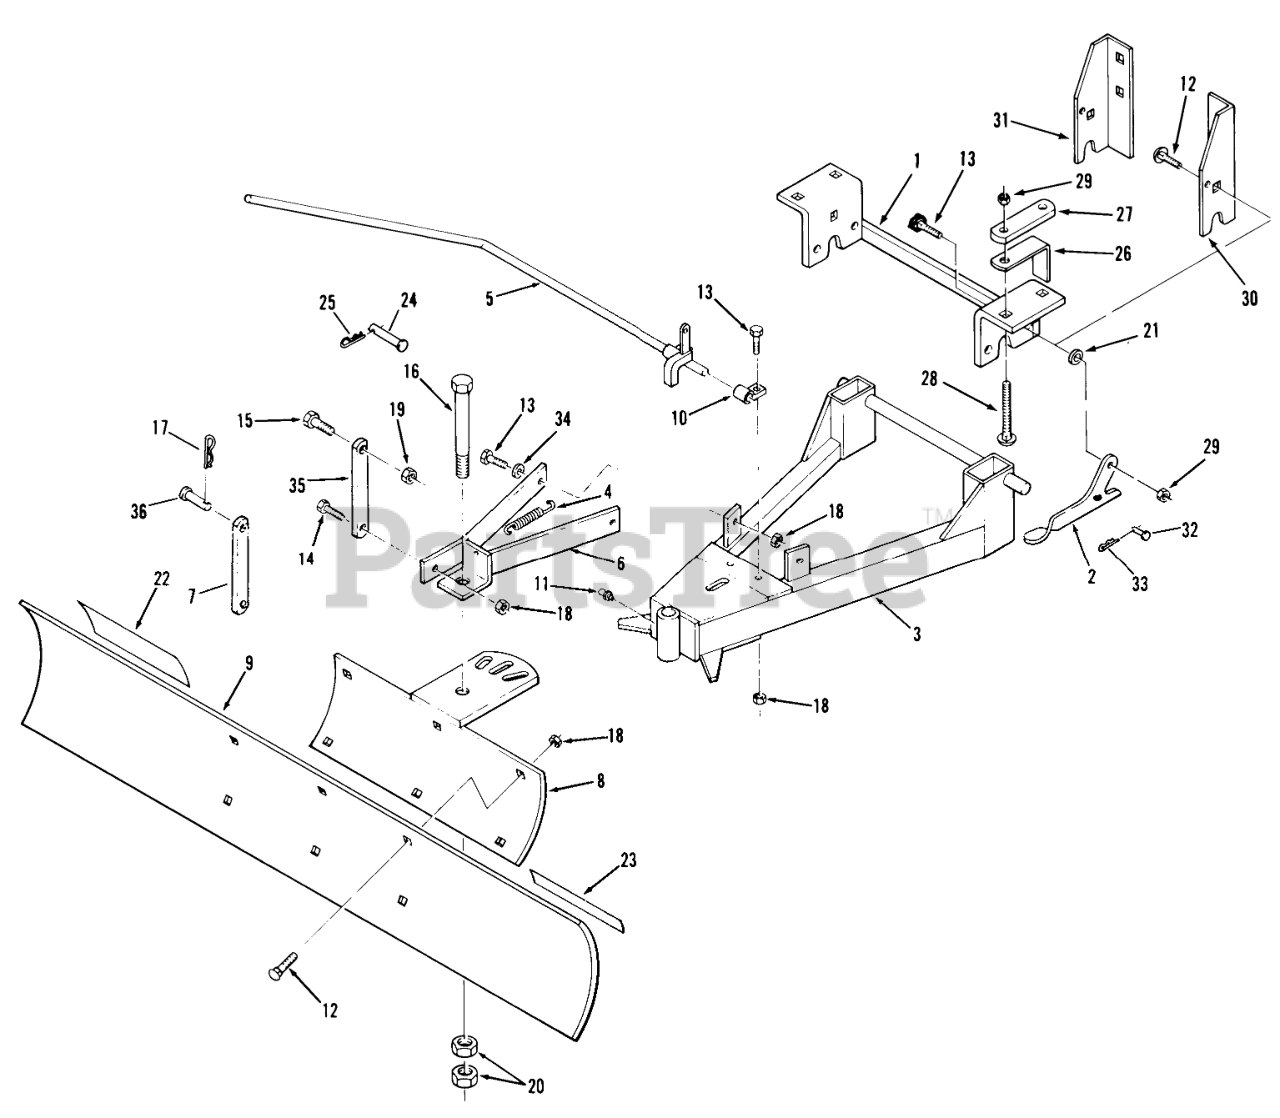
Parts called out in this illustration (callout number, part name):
1	Bracket
2	PLATE-LATCHING
3	"A" Frame Assembly
4	Spring
5	Blade Index & Lock Lever
8	PIVOT&BLADE MT (A R
9	Blade
10	Bushing-Index Lever
11	Zerk
12	Bolt
13	BOLT
14	Bolt
15	Hhcs
16	BOLT 3/4-10X5
17	Hairpin Cotter
18	Nut
19	Eslok Nut
21	Washer
22	Caution Decal
23	DECAL-WHEEL HORSE
25	Hairpin Cotter
26	SPACER-BRACKET
27	BRACKET-REAR LINK MOUNTING
28	Bolt-Carriage
29	NUT
30	BRACKET RH R
31	BRACKET LH R
32	Pin
33	Hairpin
34	Washer
35	LINK LIFT R
36	Pin
